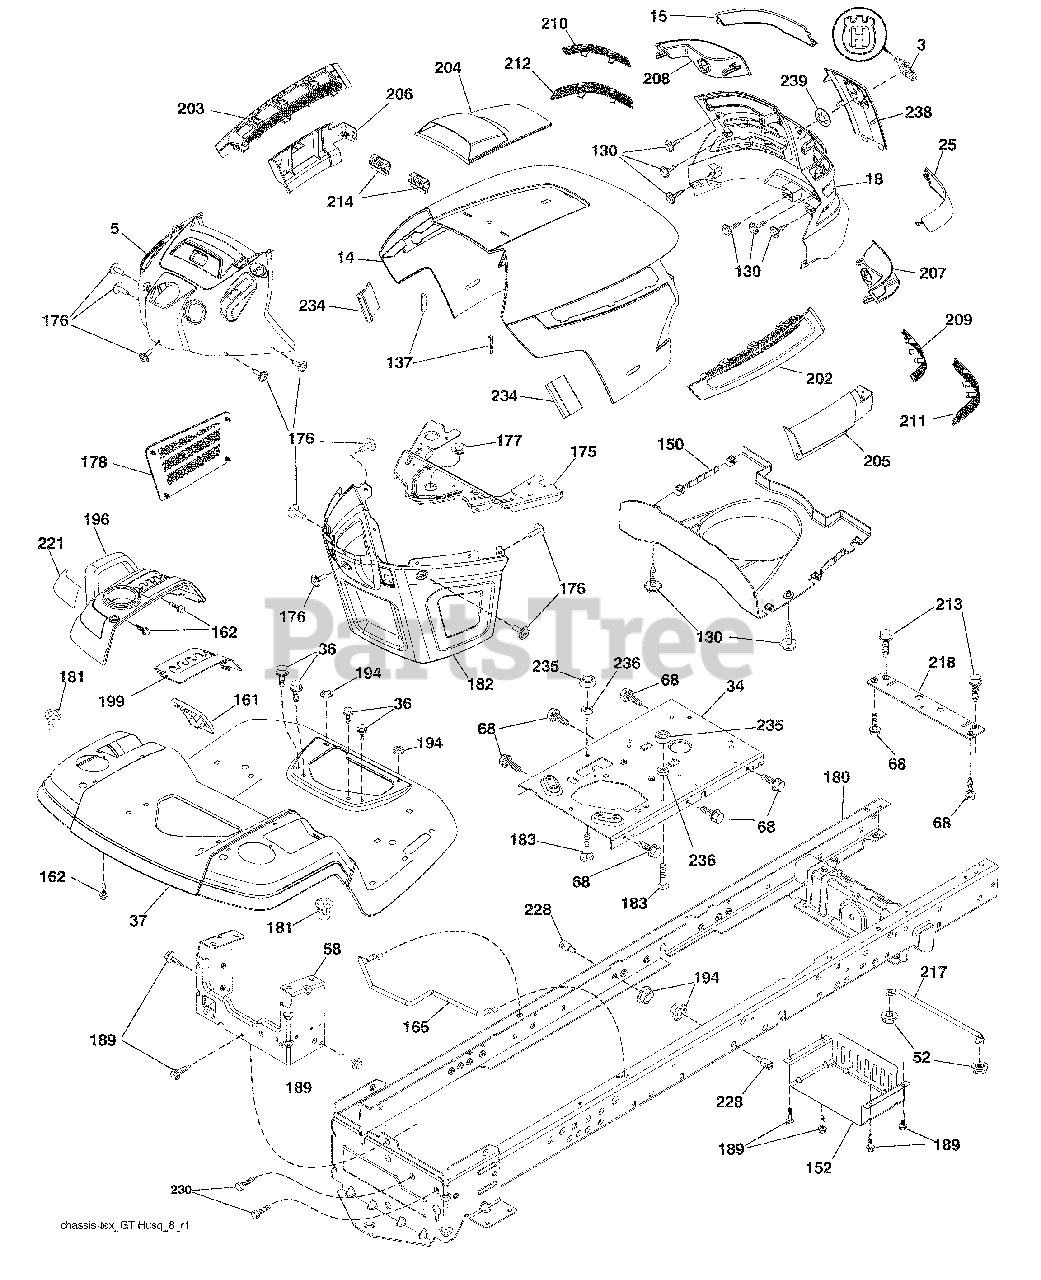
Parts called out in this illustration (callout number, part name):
3	Logo
14	Hood
34	Plate Engine
36	Screw 5/16-18 x 3/4
37	Fender
52	Nut Lock 5/16-18
58	Drawbar, Upper
68	Screw 5/16-18 x 1/2
130	Screw #10 x 0.750
137	Bumper Dash
150	Duct Heat Hood
152	Shield Browning/Debris
161	Console Fuel Window
162	Screw Hex Wsh Hi-Lo 1/4 x 1/2
165	Bracket Support Tank
175	Crossmember
176	Screw 10-24 x 5/8 Rnd Qdrx
177	Bushing Steering
178	Cargo Asm. Net
181	Bushing Mtg. Fender Crgo.
182	Dash Lower
183	Bolt 5/16-18 x 1-1/4
189	Screw 5/16-18 x 3/4
194	Nut Lock Hex Flange 5/16-18
196	Console Asm. Deck Lift
199	Plate Deck Lift
202	Vent Side Hood RH
203	Vent Side Hood LH
204	Vent Asm Hood Top
205	Skirt Hood Side RH
206	Skirt Hood Side LH
209	Insert Hex Top RH
210	Insert Hex Top LH
211	Insert Hex Bottom RH
212	Insert Hex Bottom LH
213	Bolt Hex Hd 5/16-18 unc x 3/4
214	Clip Retainer
221	Reflector LH
228	Stud Fastner
230	Bolt Shoulder
234	Bumper Hood
235	Spacer Fender
236	Nut Lock 5/16-18 unc
